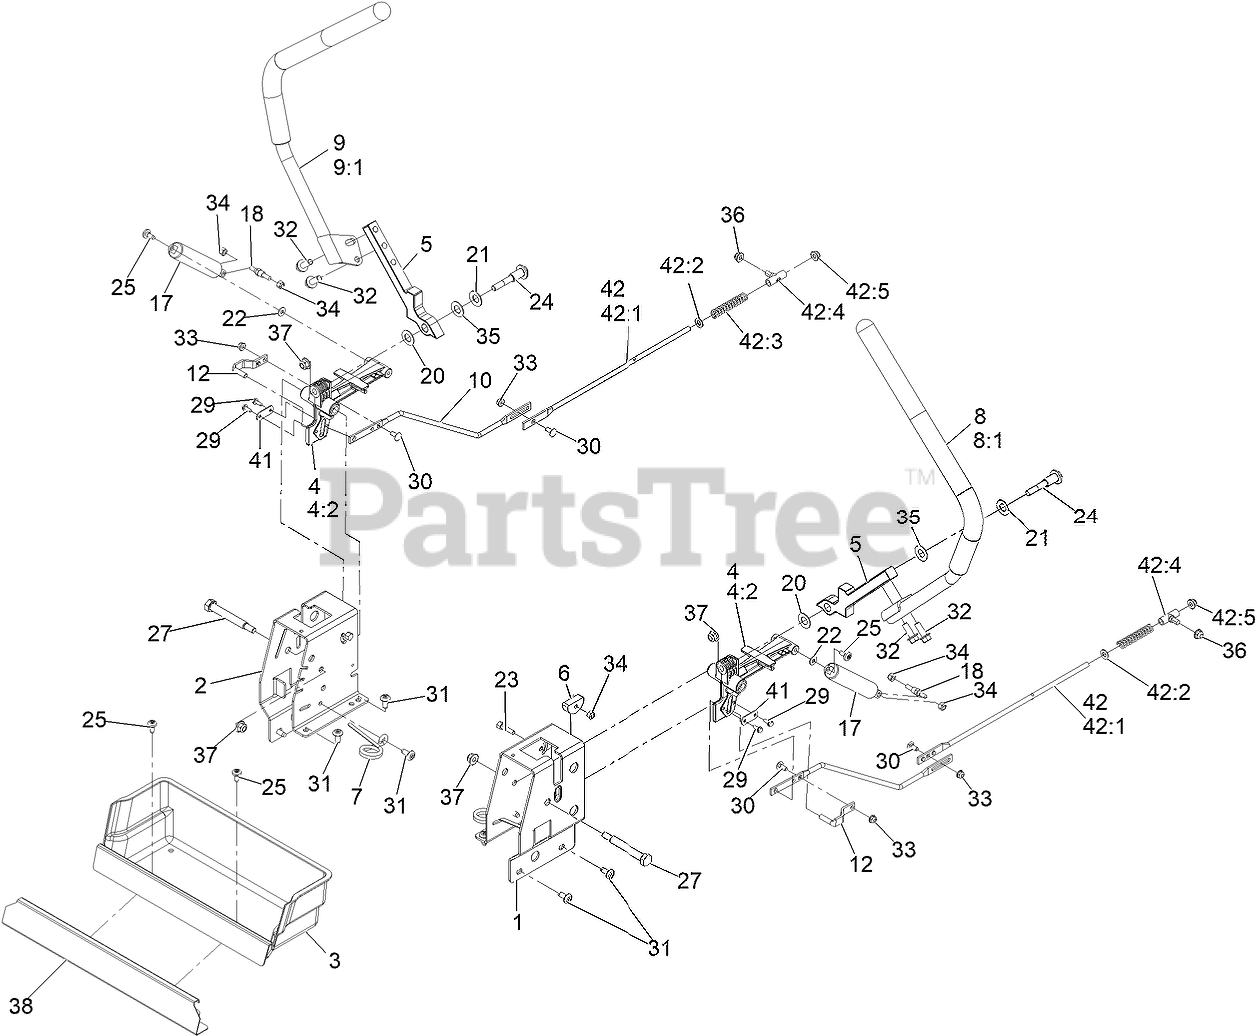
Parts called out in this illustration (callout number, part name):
1	PLATE-CONTROL BOX, LH
2	PLATE-CONTROL BOX, RH
3	BOX, STORAGE
4	ACTUATOR ARM ASM
4:2	BUSHING-FLANGE
5	ARM-CONTROL
6	ECCENTRIC
7	SPRING-TORSION
8	HANDLE-CONTROL, LH
9	HANDLE-CONTROL, RH
10	ROD-HYDRO, FRONT
12	PIN-ROD, HYDRO
17	DAMPER-NON CAVITATING
18	STUD-DAMPER
20	WASHER-NYLON
21	WASHER-BELLEVILLE
23	BOLT-PIVOT, ECCENTRIC
24	BOLT-PIVOT
25	SCREW-SHOULDER
27	BOLT-PIVOT
29	SCREW-TAPTITE
30	SCREW-CARR
32	SCREW-HHF 3/8-16 X 1
34	NUT-LOCK, NI
37	NUT-HF, NI
38	PLATE-KICK
41	PLATE-STOP, HYDRO
42	Rod Hydro ASM
42:1	ROD-HYDRO, REAR
42:2	WASHER-PLAIN
42:3	SPRING-COMPRESSION
42:4	Rod-Hydro
